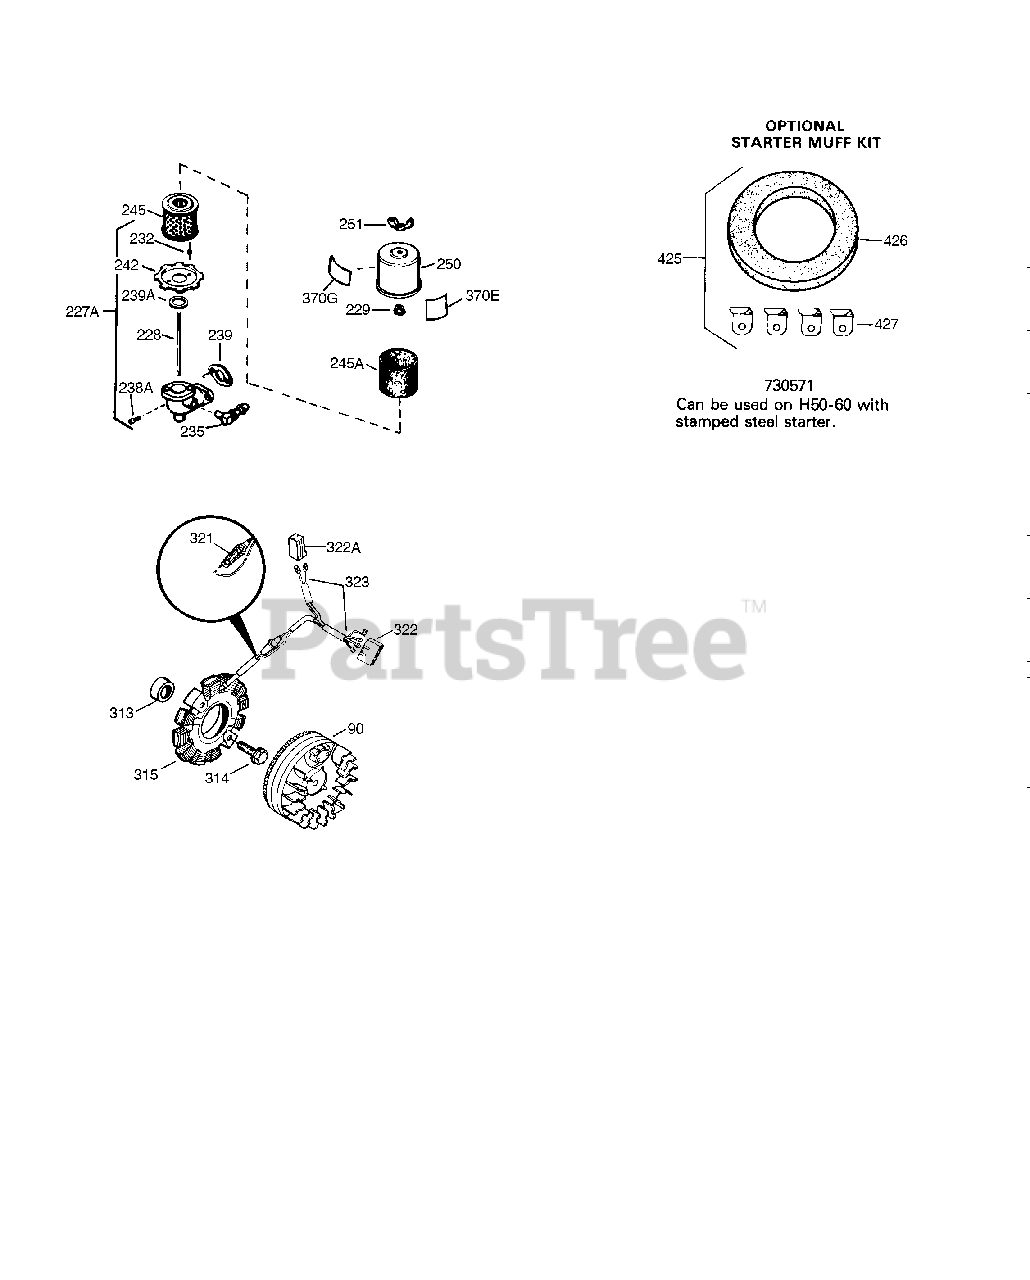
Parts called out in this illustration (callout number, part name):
90	Flywheel
129	Screw, 5/16-18 x 2-1/2"
131	Screw, 5/16-18 x 2-1/2"
239	* Air Cleaner Gasket
242	Air Cleaner Bracket
245	Air Filter
250	Air Cleaner Cover
